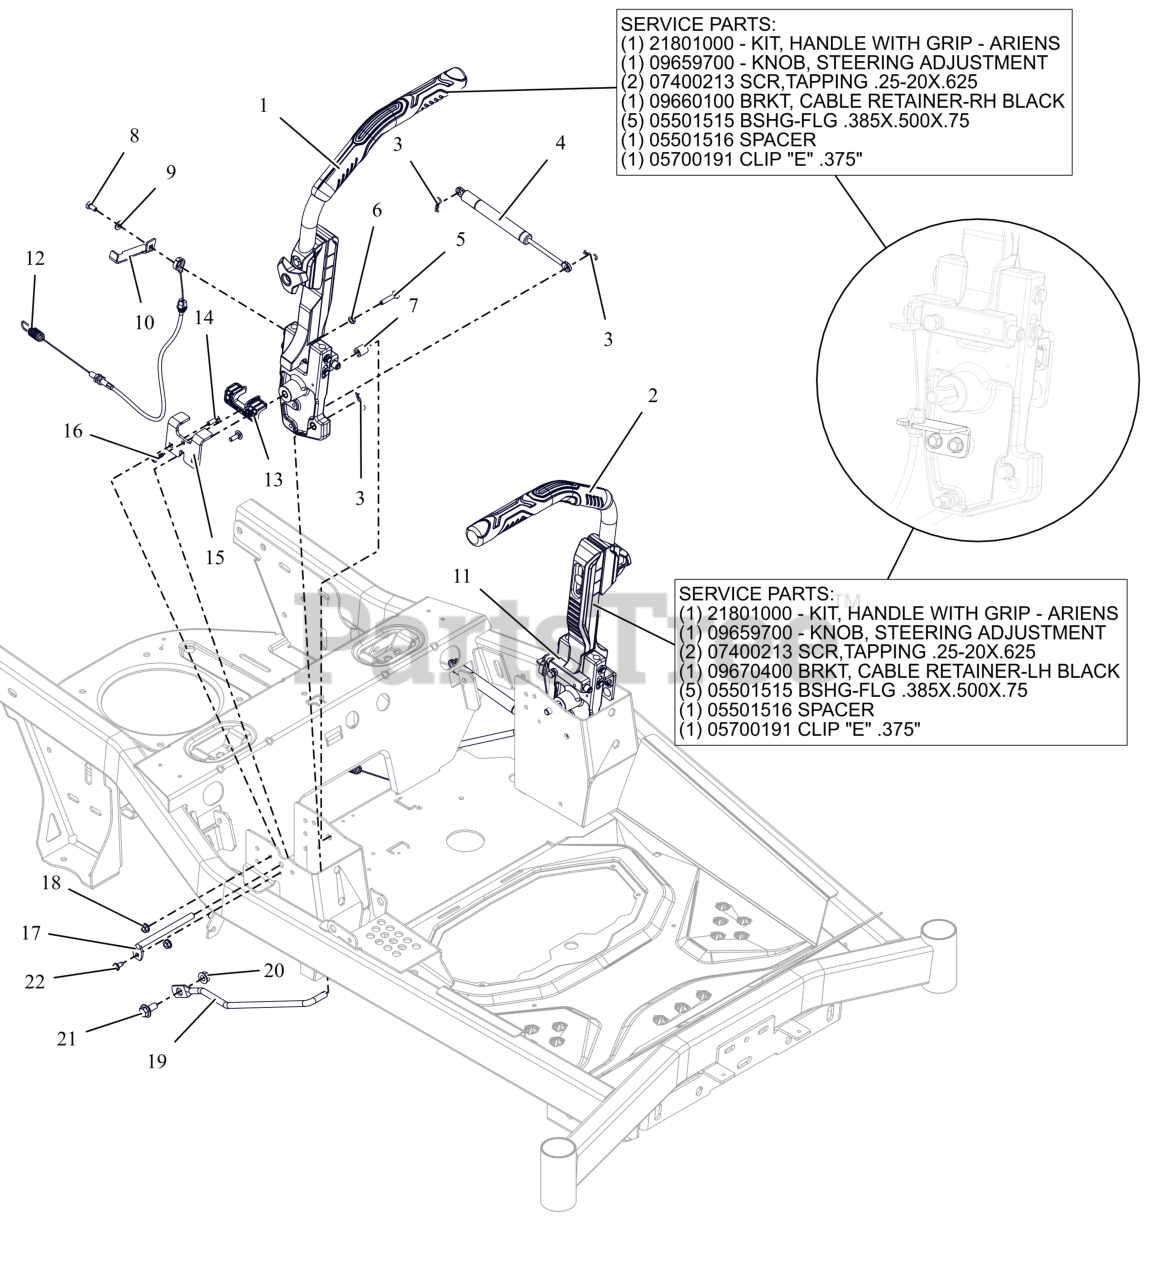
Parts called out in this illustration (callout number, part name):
1	ASM- CONTROLS -RH ARIENS
1	KIT - TUBE WITH GRIP - ARIENS
1	KNOB, STEERING ADJUSTMENT
1	SCREW, TAPPING .25X.20X.625
1	BRKT, CABLE RETAINER -RH BLACK
1	BSHG-FLG .385X500X.75
1	SPACER
1	3/8" E RETAINING RING EXTERNAL
2	ASM- CONTROLS -LH ARIENS
2	KIT - TUBE WITH GRIP - ARIENS
2	KNOB, STEERING ADJUSTMENT
2	SCREW, TAPPING .25X.20X.625
2	BRKT, CABLE RETAINER -RH BLACK
2	BSHG-FLG .385X500X.75
2	SPACER
2	3/8" E RETAINING RING EXTERNAL
3	PIN, HAIR #213 .08X1.19 ZCC
4	DAMPER- STRAIGHT MOUNT
5	BLT, HEX 0.25-20X1.25F GR5 ZCC
6	NUT-JAM .250-20 G2 ZCC
7	SPCR- SNAP-ON 1/2 X 1 1/2
8	BLT, HEX .25-20X.50 G5ZCC EP80
9	WSHR,FLT .281X.625X.065 ZCC
10	BRKT, PARKING BRK ENG R (BLACK)
11	BRKT, PARKING BRK ENG L (BLACK)
12	CABLE- PARK BRAKE
13	STEERING-PLASTIC LINER
14	BLT, RHSN .25-20X.750 G5 ZCC
15	PLATE- BRAKE STOP
16	SCR-TAP 12-14X.75PLSTITE @BLZC
17	PIN- FIXED STEERING PIVOT
18	NUT-LK-CTR-FLG .25-20 ZC120
19	WIREFORM- STEERING LINKAGE
20	NUT-LK-CTR-FLG .375-16 GF ZCC
21	BLT-SHLDR .50X.175 ZCC
22	SCR-TAP .25-20X.50 HWH ZCC
